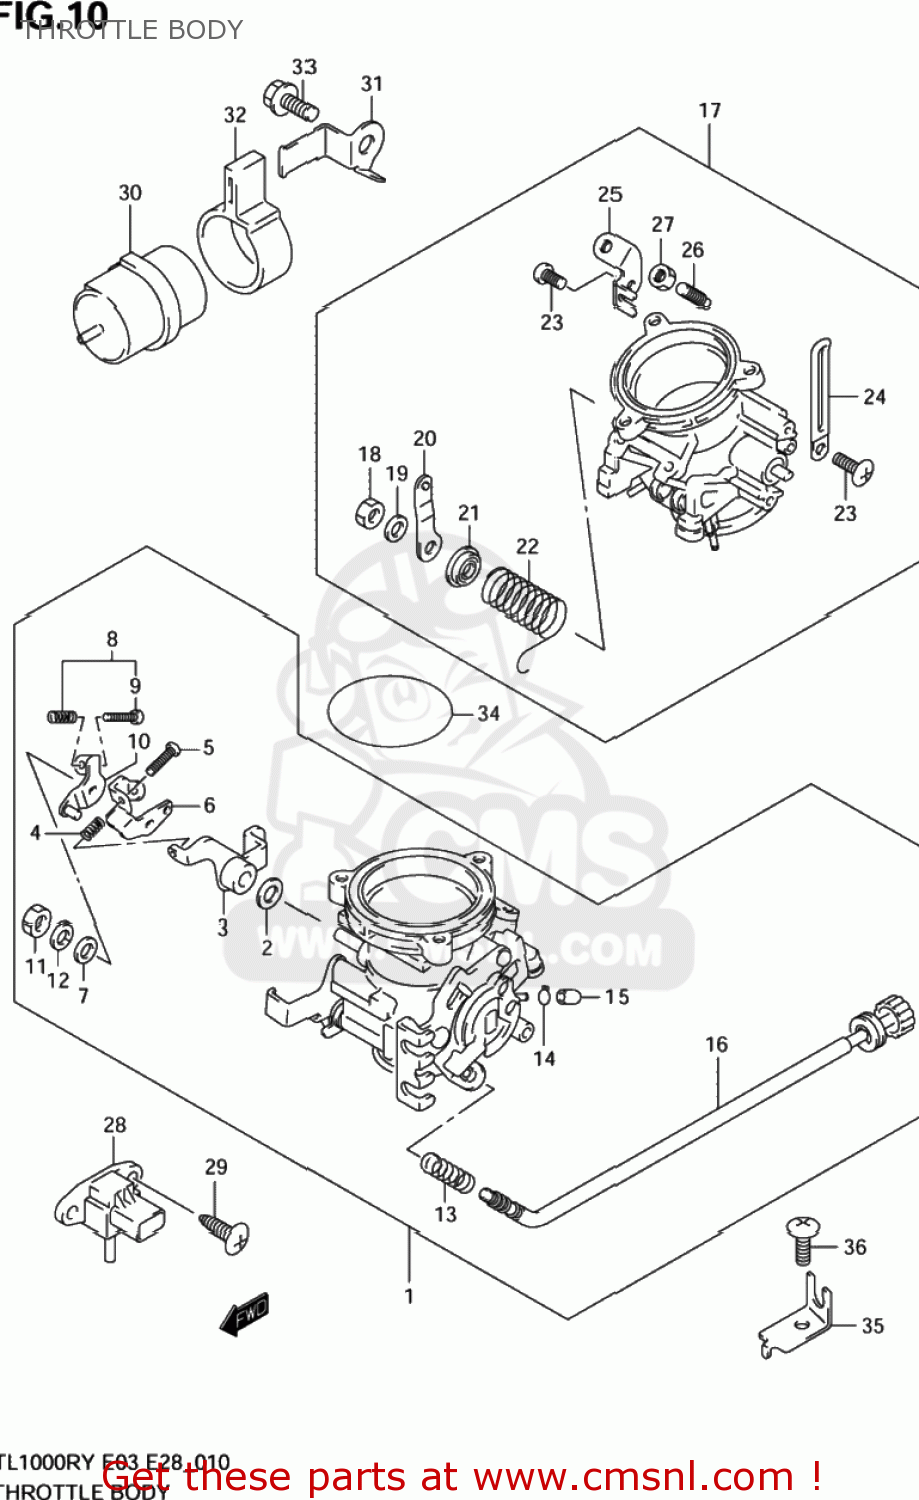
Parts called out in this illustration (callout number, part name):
1	BODY ASSY,THROTTLE FR
2	PACKING (NAS)
3	LEVER ASSY
4	SPRING
5	SCREW
6	LEVER
7	RING
8	SCREW SET,ADJUST
9	SCREW
10	LEVER ASSY
11	NUT
12	WASHER,LOCK
13	SPRING
14	CLIP
15	CAP
16	ADJUST SCREW ASSY
17	BODY ASSY,THROTTLE RR
18	NUT
19	WASHER,LOCK
20	LEVER ASSY
21	RING
22	SPRING
23	SCREW
24	CLAMP(L:65)
25	BRACKET
26	SCREW
27	NUT
28	SENSOR,MAP
29	SCREW
30	CHAMBER,VACUUM
31	PLATE VACUUM CHAMBER
32	BAND,VACUUM CHAMBER
33	PLUG(10X10)
34	O RING(D:2.4,ID:60.5)
35	PLATE,IDLE ADJUST
36	SCREW
